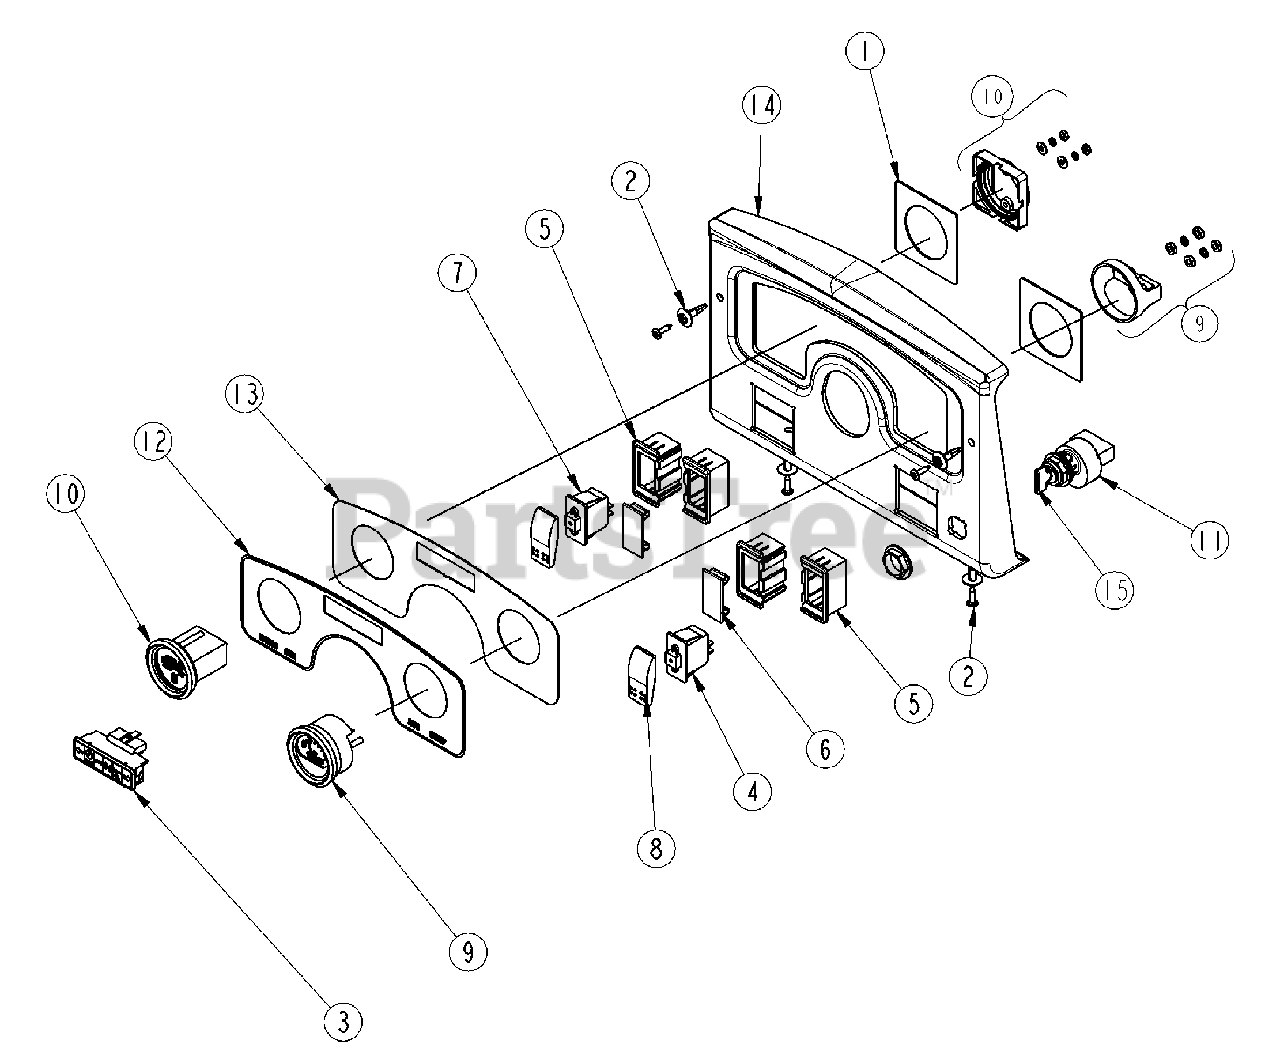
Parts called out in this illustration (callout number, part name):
1	DASH BACKER PLATE
2	RIVET, 1/4
3	INDICATOR LIGHT STRIP 8-PIN Replacement Bulb 833-418c
4	DUMP SWITCH WAYTEK 44304
5	SWITCH MOUNT END
6	PANEL PLUG
7	SWITCH ROCKER SPST
8	SWITCH ACTUATOR
9	GAUGE, VOLT METER
10	GAUGE, HOUR METER
11	IGNITION SWITCH W/2 KEYS (6PIN)
12	DECAL INSTRUMENT PANEL
13	INSTRUMENT PANEL
14	DASH TRUCK
15	KEY W/SHIELD (RP FOR 833-336C)
